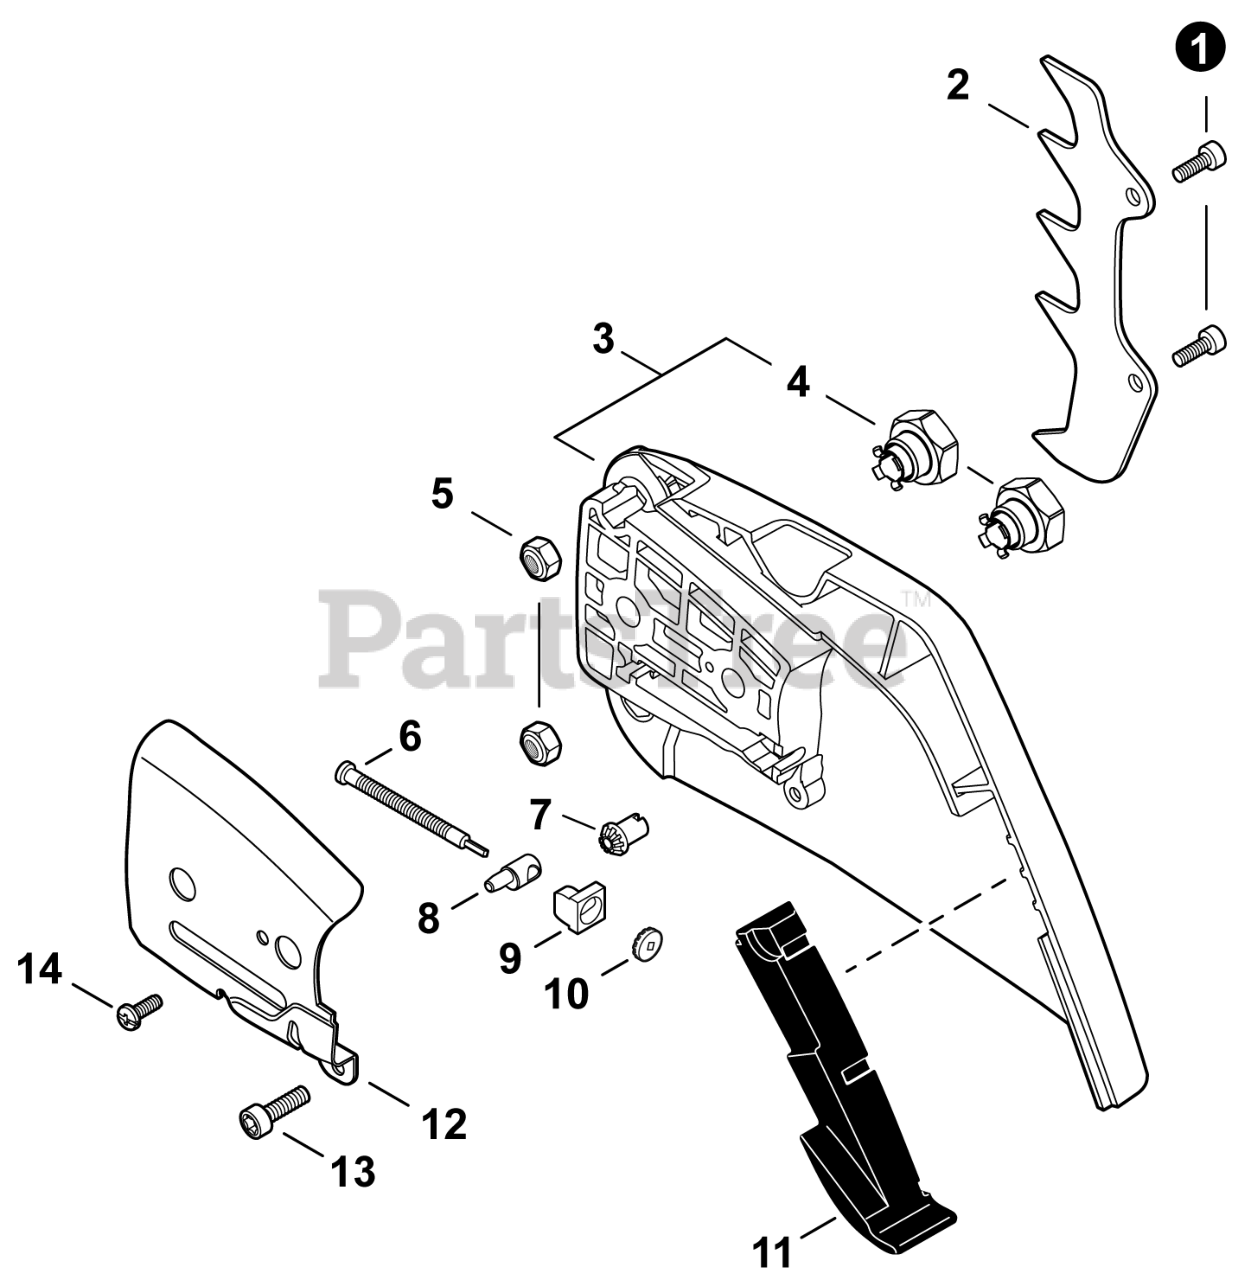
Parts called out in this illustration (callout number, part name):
1	BOLT, TORX 5x12
2	SPIKE, BUMPER
3	GUARD, SPROCKET
5	NUT, LOCK M5
6	SCREW, CHAIN TENSION 63 MM
7	GEAR, BEVEL
8	TENSIONER, CHAIN
9	COLLAR 8
10	GEAR, BEVEL
11	CUSHION
12	PLATE, GUIDE - OUTER
13	BOLT, TORX 4x12
14	SCREW 3x5
